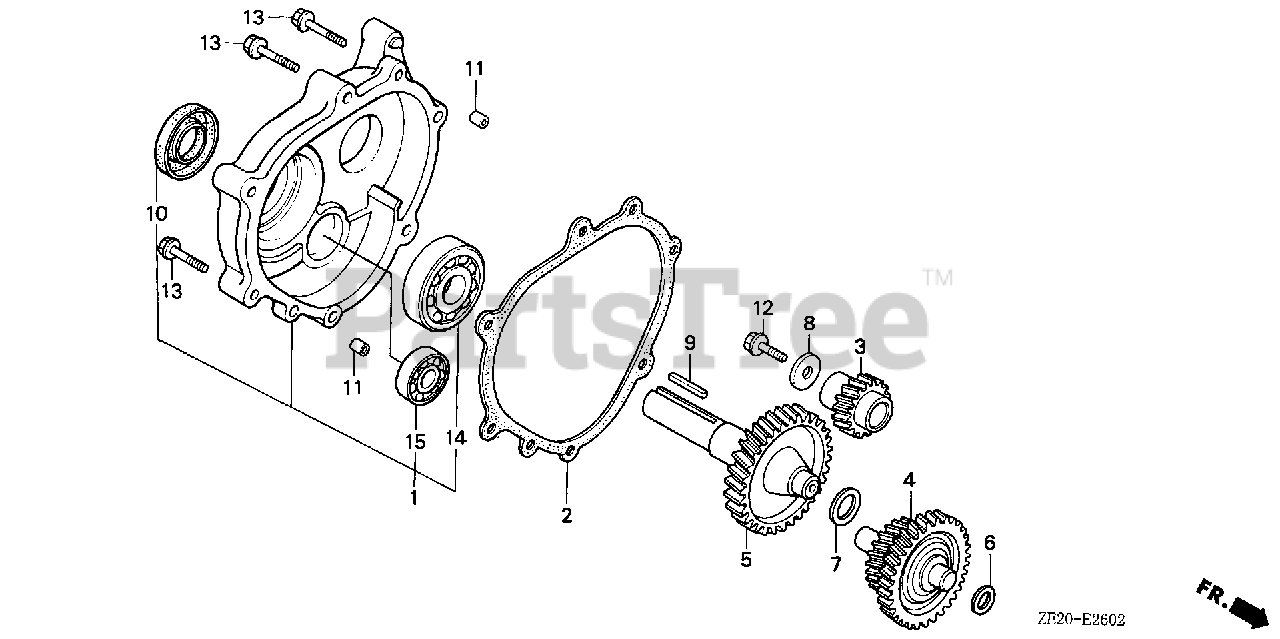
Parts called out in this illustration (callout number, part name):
1	COVER ASSY., REDUCTION CASE
2	GASKET, CHAIN CASE COVER
3	GEAR, PRIMARY DRIVE (17T)
4	COUNTERSHAFT (18T/40T)
5	SHAFT, P.T.O. (46T)
6	SHIM A
7	SHIM B
8	WASHER (8MM)
9	KEY (6.3X6.3X43)
10	OIL SEAL (30X46X8)
11	PIN, DOWEL (8X12)
11	PIN A, DOWEL (8X12)
11	PIN, DOWEL (8X14)
12	BOLT, FLANGE (8X25)
13	BOLT, FLANGE (8X40)
14	BEARING, RADIAL BALL (6206)
15	BEARING, RADIAL BALL (6302)
